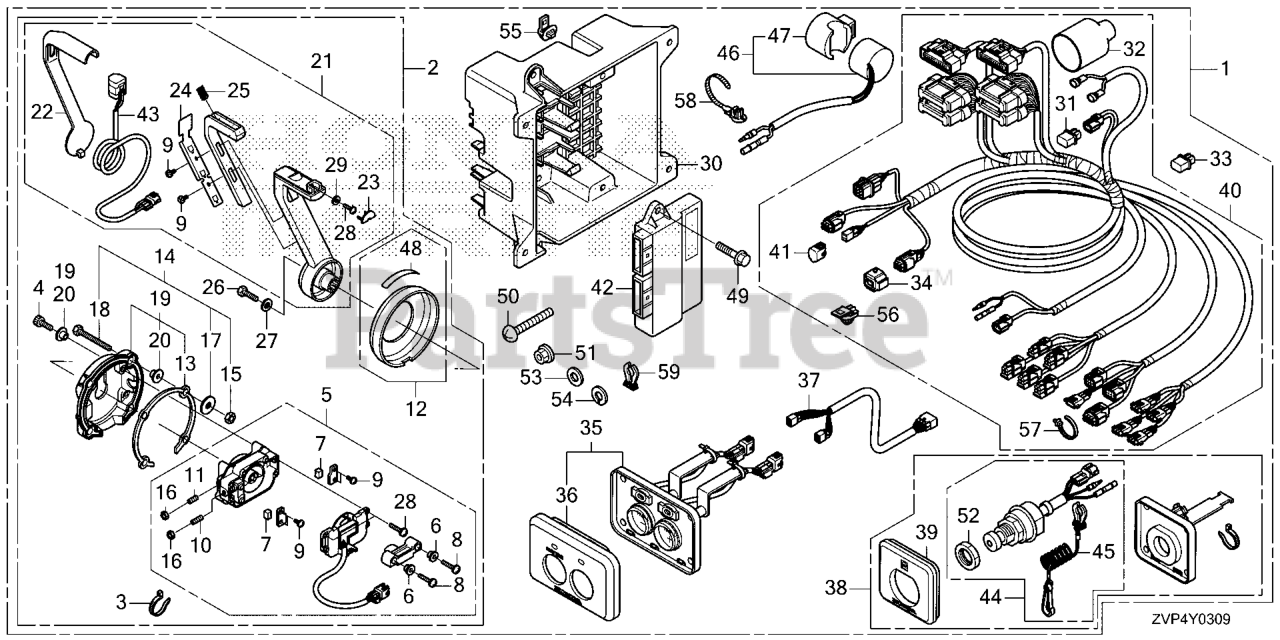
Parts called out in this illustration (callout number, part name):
1	BOX KIT, R/C (2ND)
2	BOX ASSY., REMOTE CONTROL (FLUSH MOUNT)(RH)
3	BAND, NYLON
4	BOLT, SOCKET
5	HOUSING ASSY. (FLUSH MOUNT)
6	COLLAR, STOPPER
7	SHOE, BRAKE
8	SCREW
9	SCREW
10	SCREW SET
11	SCREW SET
12	COVER ASSY. (FLUSH MOUNT)
13	SHEET, WATERPROOF (FLUSH MOUNT)
14	NUT SET, MOUNTING
15	NUT, NYLON
16	NUT
17	WASHER
18	BOLT
19	BASE ASSY. (FLUSH MOUNT)
20	COLLAR, BASE
21	LEVER ASSY. (FLUSH MOUNT)
22	PANEL, LEVER (FLUSH MOUNT)
23	CAP, LEVER (FLUSH MOUNT)
24	PLATE, LEVER PANEL
25	SPRING, COIL
26	BOLT
27	WASHER
28	SCREW
29	WASHER
30	CASE, CONTROL UNIT
31	TERMINATOR ASSY.
32	COVER, CONNECTOR (NOT AVAILABLE)
33	DUMMY, WATERPROOF CONNECTOR
34	SUSPENSION, CONNECTOR
35	PANEL ASSY., FUNCTION SWITCH
36	PANEL, FUNCTION SWITCH
37	SUB-HARNESS ASSY., FUNCTION SWITCH
38	PANEL ASSY., EMERGENCY STOP
39	PANEL, EMERGENCY STOP SWITCH
40	CABLE ASSY., REMOTE CONTROL (2ND)
41	CAP, DUMMY (WPC 4P 090 M) (RED)
42	UNIT ASSY., CONTL
43	SWITCH ASSY., POWER TRIM-TILT (FLUSH MOUNT)
44	SWITCH ASSY., EMERGENCY STOP
45	WIRE, EMERGENCY
46	BUZZER ASSY., WARNING
47	SUSPENSION, WARNING BUZZER
48	MARK, FLUSH MOUNT
49	BOLT, FLANGE (6X20)
50	SCREW, PAN (5X40) DUAL QTY = (8) (SINGLE)
51	NUT, FLANGE (5MM)
52	NUT
53	WASHER, PLAIN (5MM)
54	WASHER, SPG (5MM)
55	CLIP, CONNECTOR (DARK BLUE)
56	CLIP, CONNECTOR (DARK BROWN)
57	CLIP, HARNESS BAND (145MM) (BLACK)
58	CLIP, BAND HARNESS (152.4MM) (BLACK)
59	CLIP, EMERGENCY LOCK
